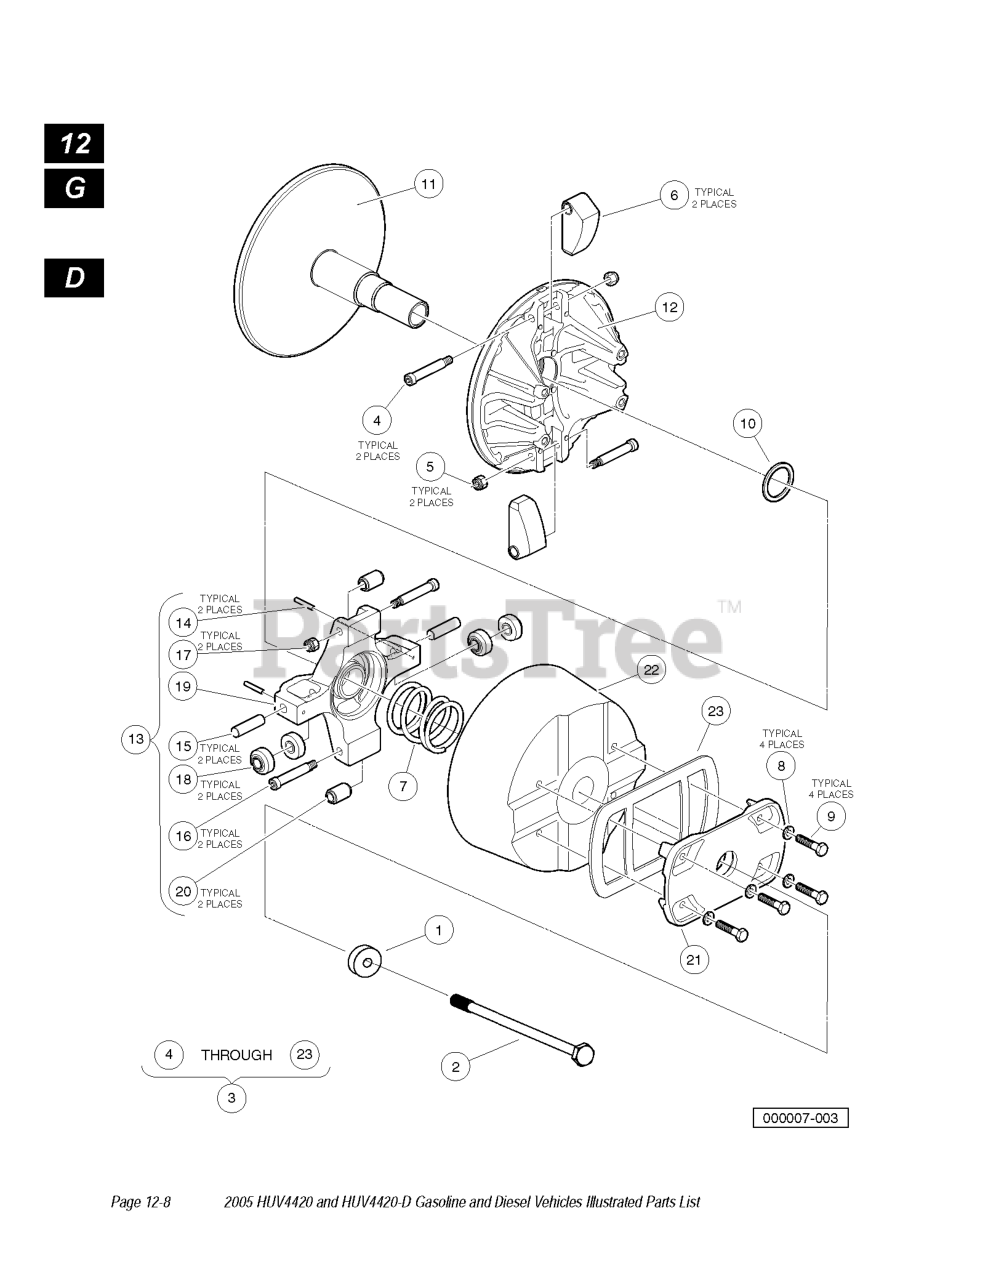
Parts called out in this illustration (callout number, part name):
1	WASHER, STEPPED, CVT PRIMARY
2	BOLT, M10X1.25X200 LOCTITE
3	CVT, PRIMARY GAS
4	SCREW, SHLDER HEX, .312 X 1.75
5	NUT, LOCK HEX, 1/14-20, FLEXLC
6	SUB ASSY, WT CLUTCH, GAS
7	SPRING, COMPRESSION, PRIMARY
8	WASHER, LOCK, H SPRING, 1/4
9	SCREW, CAP, HEX HD, 1/4 X 1.25
10	SHIM, 1.63 X 1.33
14	PIN, SPRING SLOTTED,1.25 X 1.0
15	PIN, DOWEL, .375 X 1.50
16	SCREW, SHLDER HEX, .312 X 1.75
17	NUT, LOCK HEX, 1/14-20, FLEXLC
18	ROLLER, TORQUE, GAS
20	SUB ASSY, ROLLER WEIGHT
22	COVER, CLUTCH, 4X4
23	GASKET, COVER, CLUTCH, 4X4
